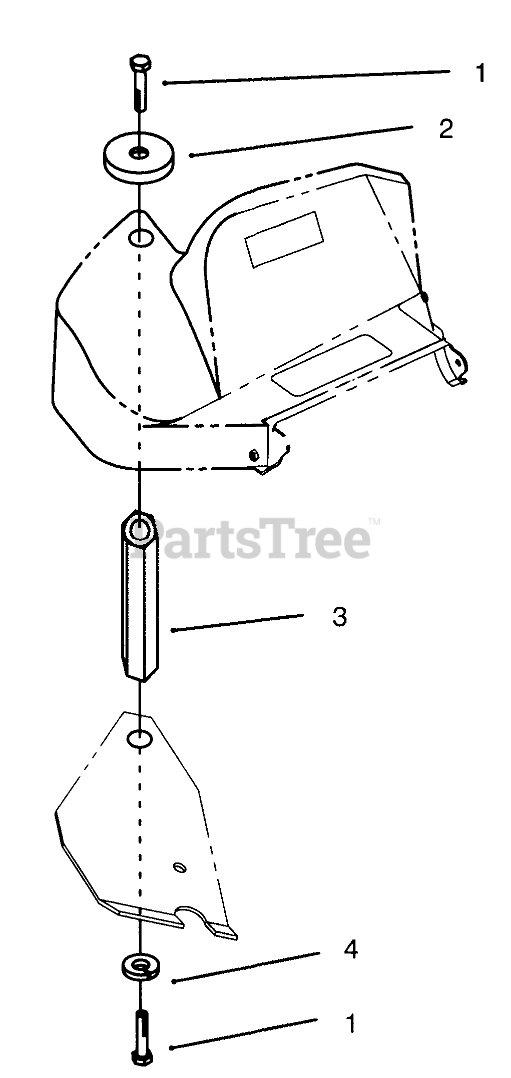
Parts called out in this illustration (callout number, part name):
1	SCREW-HH
2	WASHER-FLAT
3	SHAFT - VAC BAGGER
4	WASHER-LOCK
